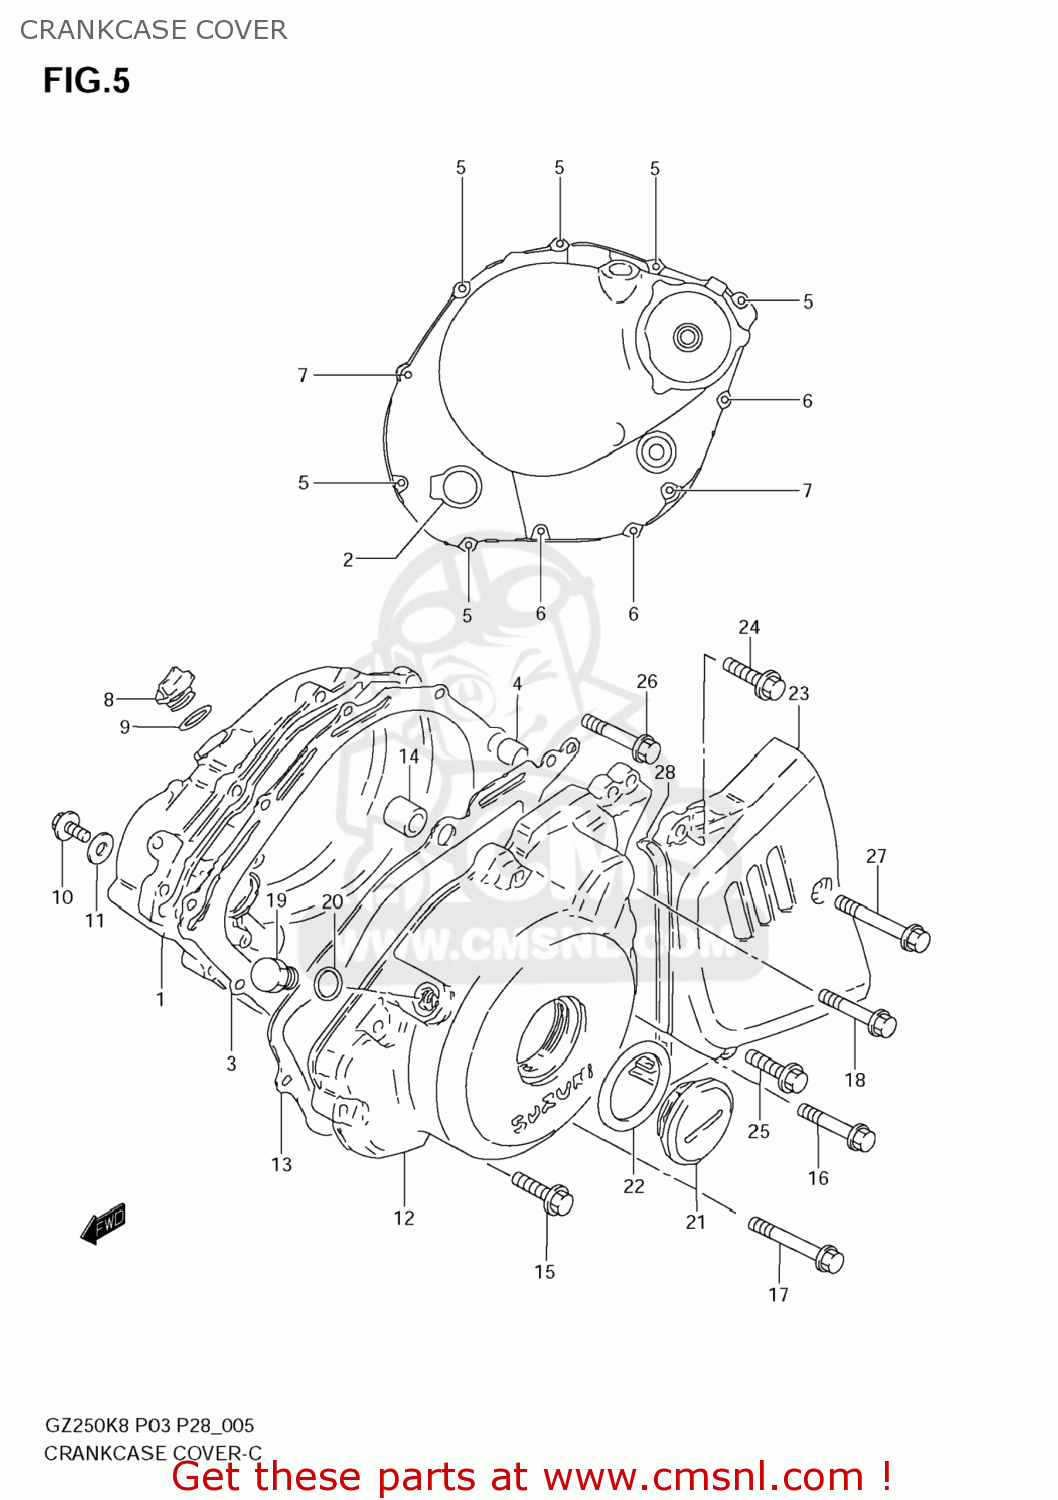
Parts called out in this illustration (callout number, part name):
1	COVER,CLUTCH
2	LENS,OIL LEVEL CHECK
3	GASKET,CLUTCH COVER (NAS)
4	PIN
5	BOLT(6X25)
6	BOLT(6X35)
7	BOLT(6X45)
8	PLUG(20X10)
9	O RING(D:3.1,ID:16.8)
10	PLUG (14X12)
11	GASKET(13.8X18.8X4.8) (NAS)
12	COVER,MAGNETO
13	GASKET,MAGNETO COVER (NAS)
14	PIN
15	BOLT(6X25)
16	BOLT(6X35)
17	BOLT(6X50)
18	BOLT(6X60)
19	PLUG,12X9
20	GASKET(12.1X16.2X3.7) (NAS)
21	PLUG,36X10
22	O RING(D:3.1,ID:32.7)
23	COVER,ENGINE SPROCKET
24	BOLT(5X20)
25	BOLT
26	BOLT(5X30)
27	BOLT(5X45)
28	DAMPER,ENGINE SPROCKET COVER
